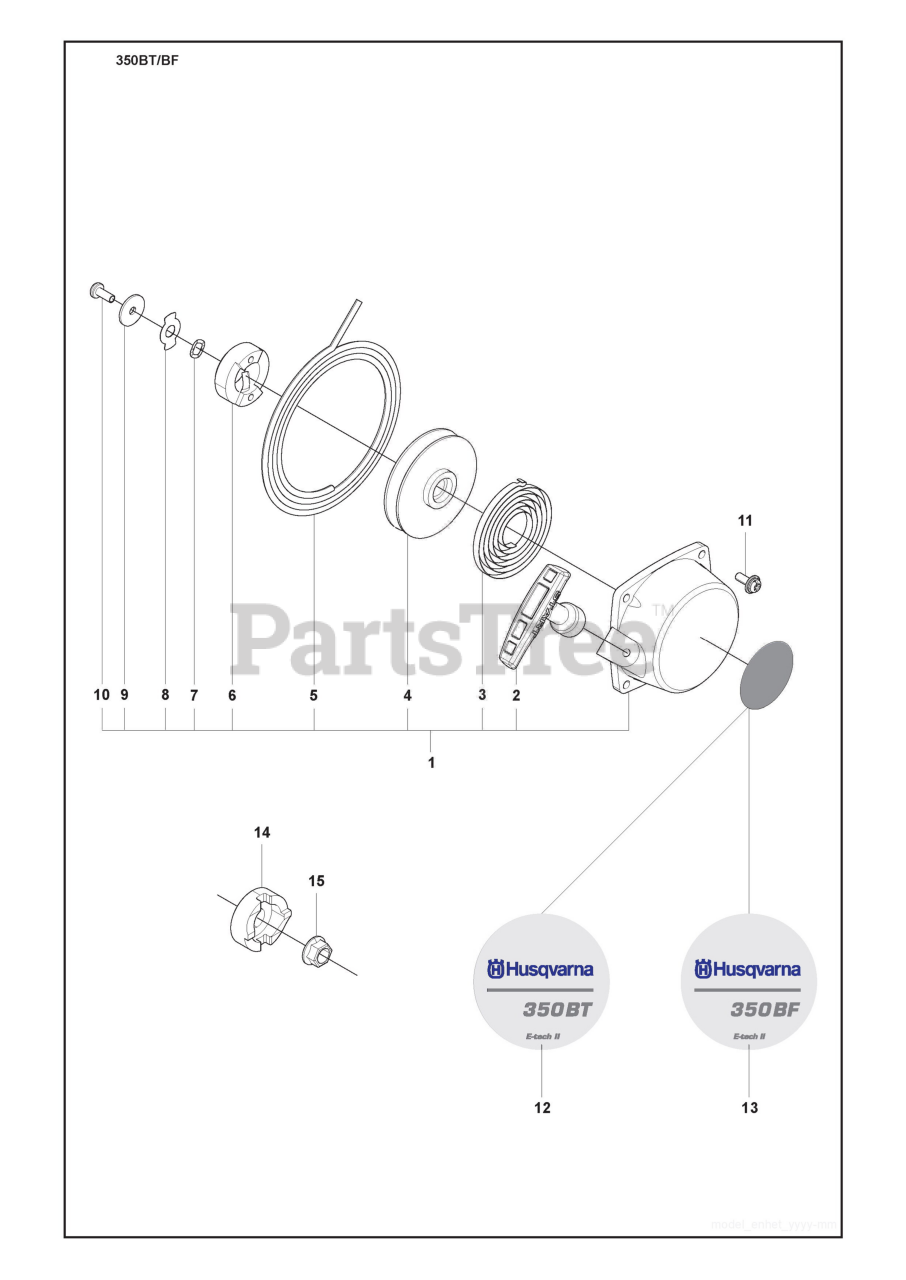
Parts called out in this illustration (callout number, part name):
1	STARTER ASSY
4	STARTER PULLEY
6	STARTER PAWL
8	RETAINER
9	WASHER
12A	LABEL, RECOIL 350BT
12B	LABEL, STARTER
13	STARTER PAWL
14	NUT
